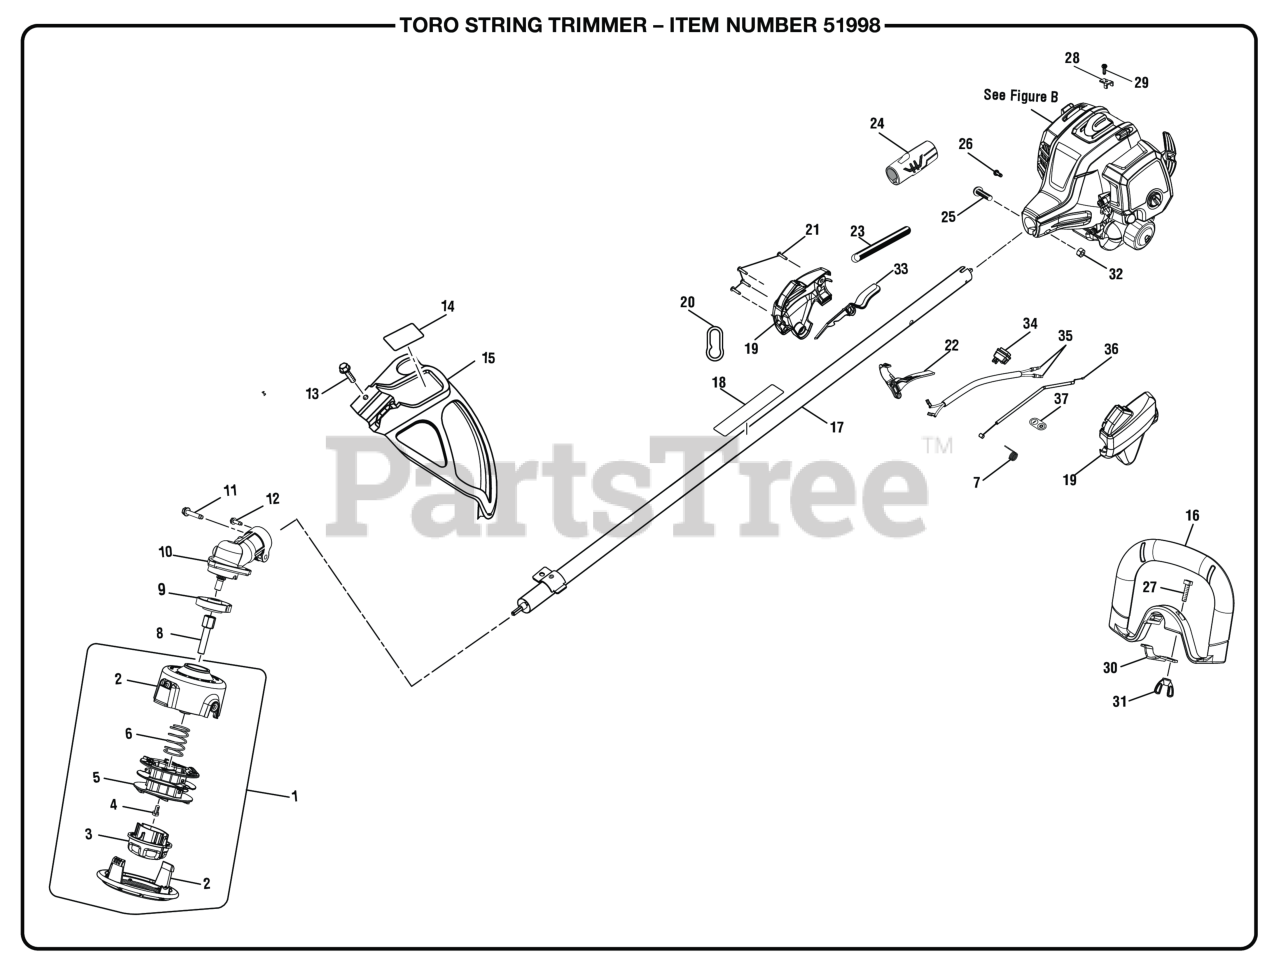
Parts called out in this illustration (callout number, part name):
1	Trimmer Head Assembly (.095)
2	Stringhead Housing
3	Bump Knob
4	Screw (5/16 x 1/2 in., Left Hand)
5	Spool Assembly
6	Compression Spring
7	Torsion Spring (Throttle Trigger)
8	Trimmer Head Shaft Adaptor
9	FLANGED WASHER
10	Gear Head Assembly
11	Screw (1/4-20 x 1-1/4 in., Hex Washer Hd. S.T.)
12	Screw w/Washer (10-24 x 5/8 in., Hex Hd. T.F.)
13	SCREW (#1/4-20 X 1-1/4 in. HEX WASHER HD.)
14	Grass Deflector Label
15	Grass Deflector Assembly
16	Front Handle w/Grip
17	Upper Boom Assembly
18	Icon Warning Label
19	Control Handle Assembly
20	Shoulder Strap Hook
21	Screw (M4 x 20 mm, T20 Torx Pan Hd. S.T.)
23	Corrugated Tube (225 mm)
24	Rear Handle Grip
25	Screw (M6 x 30 mm, T27 Torx Button Hd.)
26	Screw (M4 x 8 mm, T25 Torx Pan Hd. T.F.)
27	Bolt (1/4-20 x 1 in., Square Hd.)
28	THROTTLE CABLE CLAMP
29	Screw (M4 x 16 mm, T20 Torx Pan Hd. S.T.)
30	Front Handle Clamp
31	Wing Nut (1/4-20, Plastic)
32	Hex Nut (M6.3 x 1)
33	Trigger Lock
34	On/Stop Switch
35	Lead Assembly
36	Throttle Cable
37	On/Stop Label
